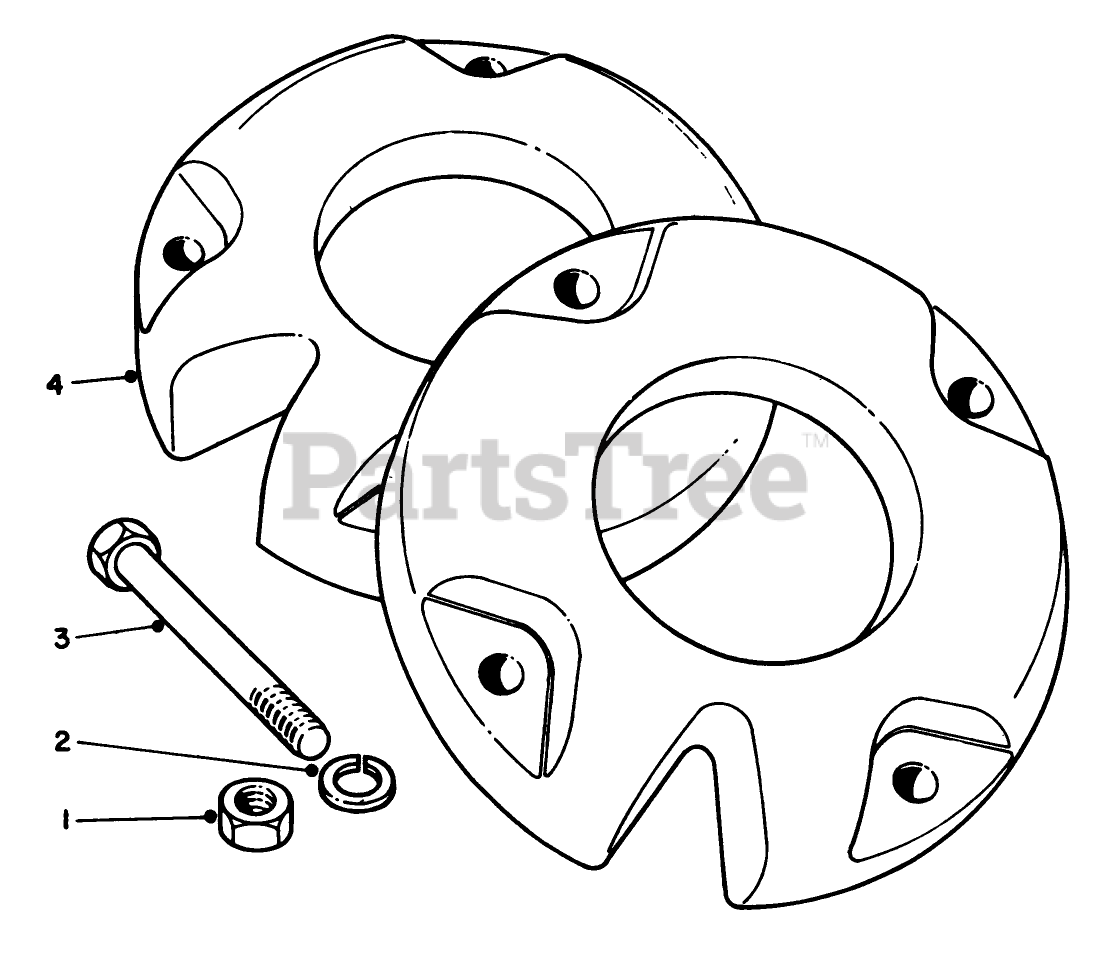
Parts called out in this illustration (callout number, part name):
1	NUT-JAM
2	WASHER-LOCK
3	Capscrew
4	Weight-Wheel
